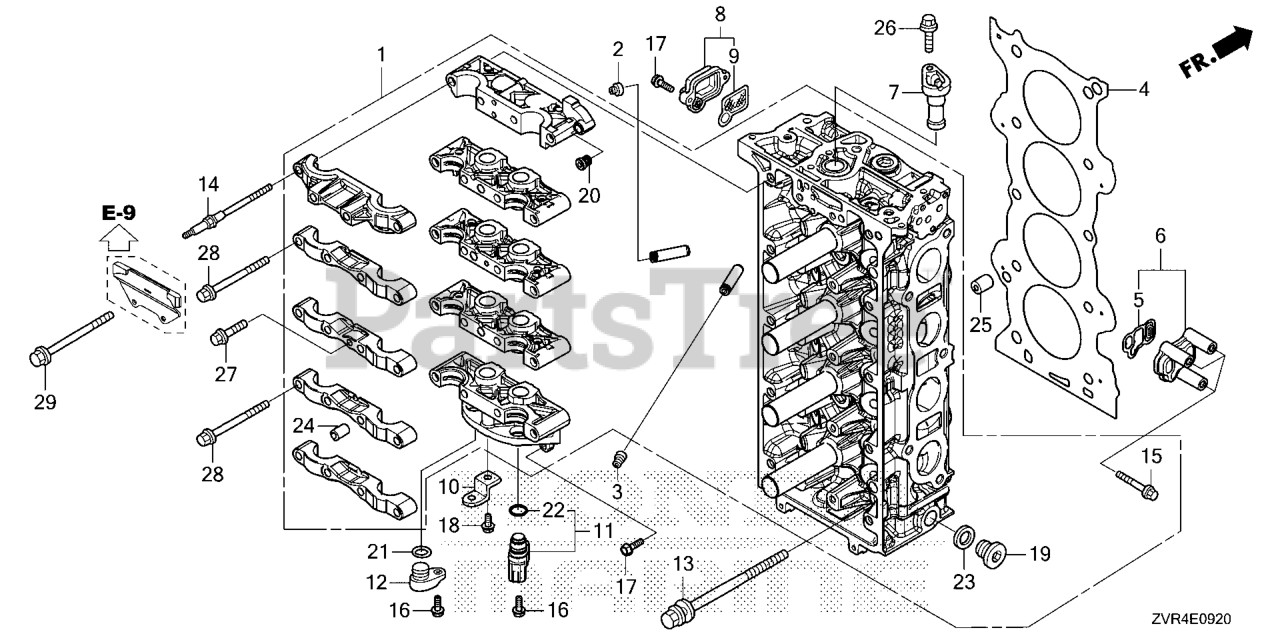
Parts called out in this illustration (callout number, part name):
1	CYLINDER HEAD KIT *NH8* (DARK GRAY)
2	SEAL A, VALVE STEM (NOK)
3	SEAL B, VALVE STEM (NOK)
4	GASKET, CYLINDER HEAD
5	FILTER ASSY., SPOOL VALVE
6	COVER ASSY., OIL PASSAGE
7	PLUG, VTC HOLE
8	STRAINER ASSY., VTC *NH8* (DARK GRAY)
9	FILTER ASSY., VTC
10	BRACKET F, CLIP
11	SENSOR ASSY., TDC
12	PLUG, TDC HOLE
13	BOLT-WASHER (11X155)
14	BOLT A, HEAD COVER
15	BOLT, FLANGE (6X52)
16	BOLT, FLANGE (6X16)
17	BOLT, FLANGE (6X20)
18	BOLT, FLANGE (6X14)
19	BOLT, SEALING (20MM)
20	BOLT, SEALING (10MM)
21	O-RING (15X1.9)
22	O-RING (15X1.9)
23	WASHER, DRAIN PLUG (20MM)
24	PIN A, DOWEL (10X16)
25	PIN A, DOWEL (14X20)
26	BOLT, FLANGE (6X20)
27	BOLT, FLANGE (6X32)
28	BOLT, FLANGE (8X90)
29	BOLT, FLANGE (8X110)
